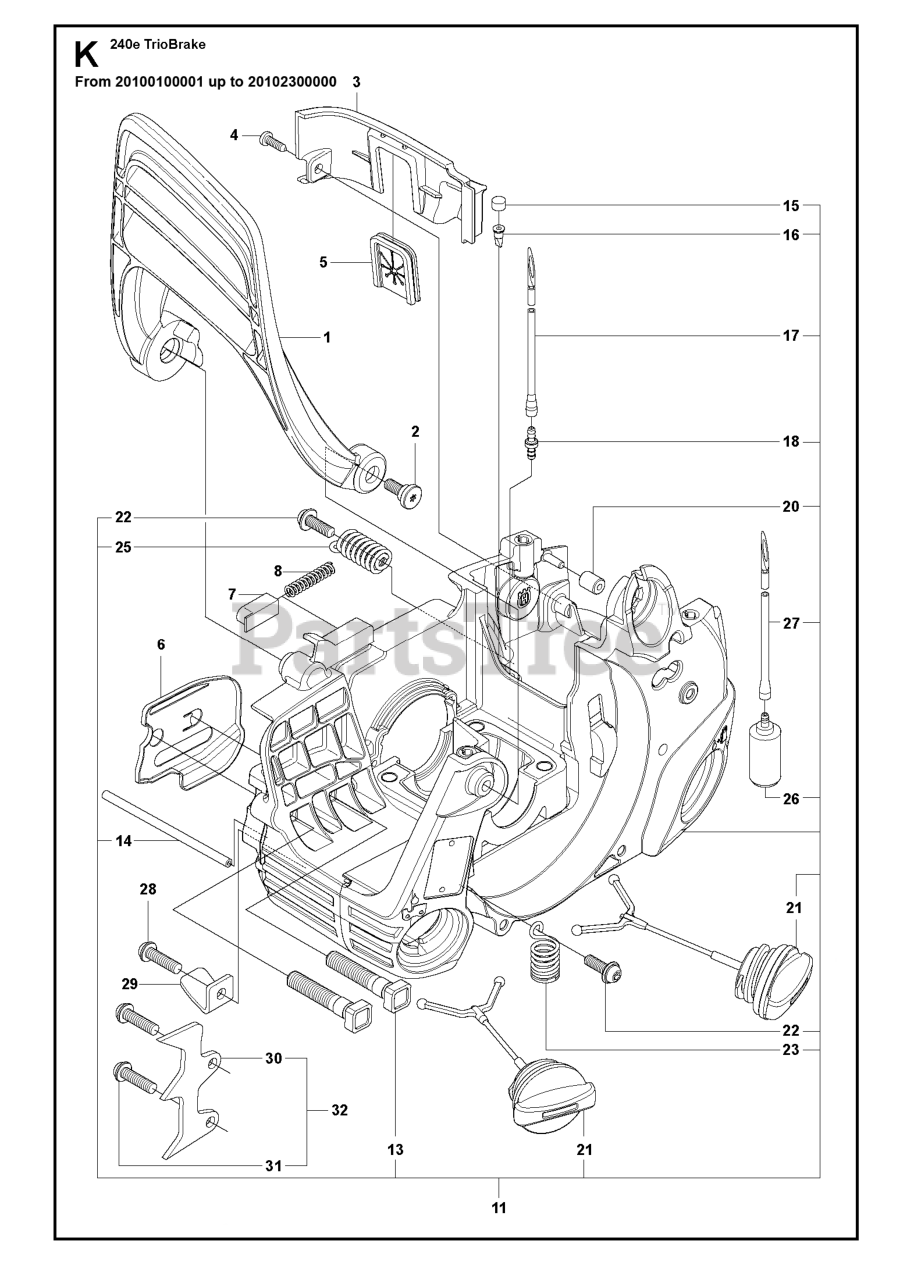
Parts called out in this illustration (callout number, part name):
1	HAND GUARD HHS
2	BOSS SCREW
7	CAP, SPRING HANDGUARD
11	CHASSIS ASSY
13	BOLT
15	VENT,FUEL TANK 36/41
16	VALVE-CHECK (DUCKBILL)
17	LINE KIT
18	FUEL LINE FITTING
20	ISOLATOR FILTER HOUSING
21	FUEL CAP W/ RETAINER
22	SCREW,FRONT HBAR 36/41
26	ASSY FUEL PICKUP PRE FLUSHED
29	CHAIN CATCHER 36/41
30	SPIKE
32	SPIKE 36/41
